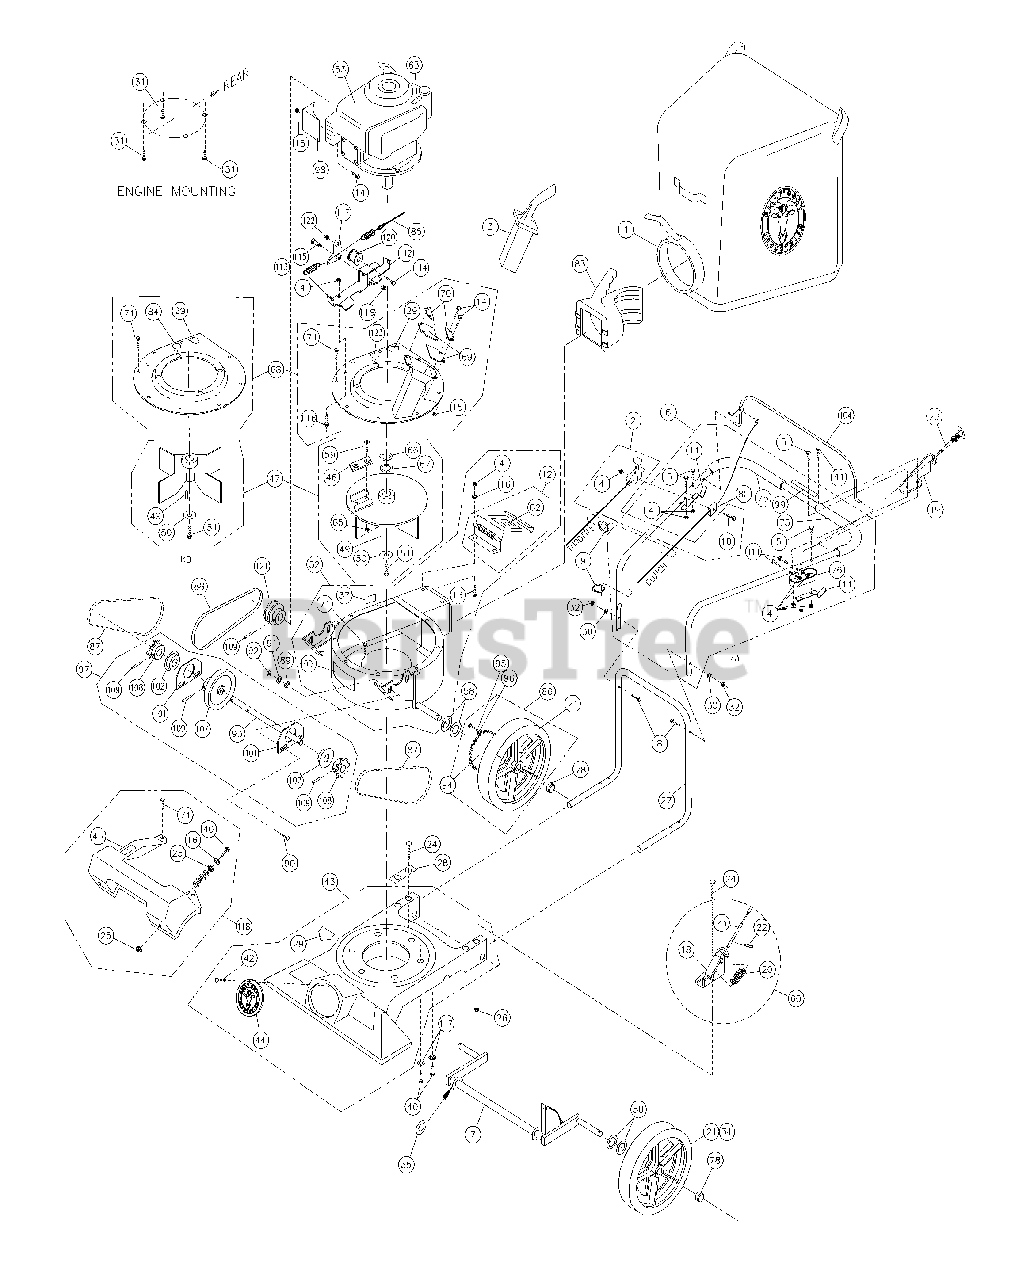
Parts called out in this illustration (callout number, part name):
1	Debris Bag Turf (service)
2	Throttle Assembly (INCL. 1 ea. 4,10)
3	Part Not Applicable on this model
4	Nut Lock (1/4 - 20)
5	Screw Cap (1/4 - 20 x 1- 1/2 HEX)
6	Handle Assy' (incl. items 4(6), 5(4), 11(2), 75(2), 76 & 99)
7	Axle Rear - Frame W.A.
8	Screw Handle 5/16 - 18 x 1-3/4
9	Clamp Cable Plastic 1"
10	Screw Cap (1/4 - 20 x 2- 1/4)
11	Bar Support Bag
12	Door Exhaust Assy' (incl. item 62)
13	Bolt - Carriage 1/4 x 3/4
14	Screw Cap #10 - 24 x 5/8
15	Part Not Applicable on this model
16	Washer 1/4 FC ZP
18	Bracket - Height Adjustment
19	Plate Upper height Adjustment
21	Tire - Only (per assy') Treaded
22	Pin - Hair Cotter
23	Cable Height Adjustment
24	Bolt - Carriage 5/16 - 18 x 4-1/2
25	Nut Lock Flange 1/4 - 20
26	Nut Lock 5/16 - 18 HEX
27	Handle Lower
28	Plate Handle Support
29	Label Danger Cut Finger
30	Washer Flat Cut 5/16
31	Screw Cap 3/8 - 16 x 2-1/2 Washer Face
34	Wheel Ass'y Cast (incl. items 21) treaded
35	Washer 0.75 "C"
37	Label Ear Eye Breathing
40	Screw Cap 1/4 - 20 x 1-1/4
41	Screw Cap 1/4 - 20 x 1-3/4
42	Screw Self Tapping 10 - 24 x 1/2
43	Nozzle Frame (incl. one of items 29,44,42)
44	Plug
45	Label Oil Chain
46	Part Not Applicable on this model
47	Impeller Ass'y (incl items 49, 50, 51)
48	Label Chipper
49	Key 3/16 Sq. x 1.25
50	Washer Lock 3/8 Twisted Tooth
51	Screw Cap 3/8-24 x 1 1/2" (Torque 50 ft.lbs.(68 Nm))
52	Housing Ass'y (incl. items 12, 14, 15, 16, 37, 100)
53	Engine 5.5 H.P. Briggs & Stratton
57	Washer 1/2 flat KD Wheel
58	Washer Flat 1/2 SAE
59	Part Not Applicable on this model
60	Height Adjustment Ass'y (incl 18, 20, 22, 23)
62	Label Danger Flying Material
63	Label Hot Engine
65	Part Not Applicable on this model
66	Part Not Applicable on this model
67	Part Not Applicable on this model
68	Plate Top Ass'y (incl. items 29, 71, 84)
69	Part Not Applicable on this model
70	Part Not Applicable on this model
71	Screw Cap 1/4-20 x 1/2 HWH
73	Knob Wing 5/16 - 18" Thin Ht.
74	Nut Lock5/16 - 18 Thin Ht.
75	Grip Handle
76	Part Not Applicable on this model
78	1/2-13 Cap nut np W/patch
83	Connector Quick
84	Label - Warning Guards
85	Cable Ass'y Clutch
86	Wheel With Sprocket Ass'y Cast ( 21, 94, 95, 96)
87	Chain 52 Pitch
88	Belt 4L220
89	Nut Whiz 1/4-0 Wash Face
90	Bolt Carriage 5/16 - 18 x 3/4
91	Washer Spring Lock 5/16
92	Nut Regular 5/16 - 18
93	Jackshaft
94	Sprocket (per Assemby) (size # 65A26) 26 Teeth
95	Screw Self Tap 1/4-14 x 3/4 (Per Assembly)
96	Washer Lock External Tooth (Per Assembly)
97	Jackshaft Ass'y (incl. 93, 101, 102, 107, 108, 109)
98	Shield Muffler TKDSP
99	Label Clutch
100	Label - Warning Guards
101	Bearing Plate
102	Bearing Ball (with Snap Ring)
104	Rod Bail Clutch
106	Screw 8122082
107	Pulley 3"OD x 5/8 Bore
108	Sprocket - 8 Tooth
109	Roll Pin 3/16 Dia. x 1 1/4 Lg.
110	Locknut 5/16 - 18 Flange
111	Part Not Applicable on this model
112	Bracket Clutch KDSP
113	Spring Tension
114	Bolt Idler
115	Bolt Shoulder 3/8" x 1/2"
116	Screw Cap 1/4 - 20 x 3/4 Lg.
117	Arm Idler Wa KDSP
118	Guard Chain Ass'y TKDSP
119	Nut Lock 5/16-18 Thin
120	Pulley Idler 1.13"OD x 3/8" Bore
121	Pulley 1.63" OD X 1/2 Bore
122	Nut Lock 3/8-16 Thin
123	Label Read Owner's Manual
